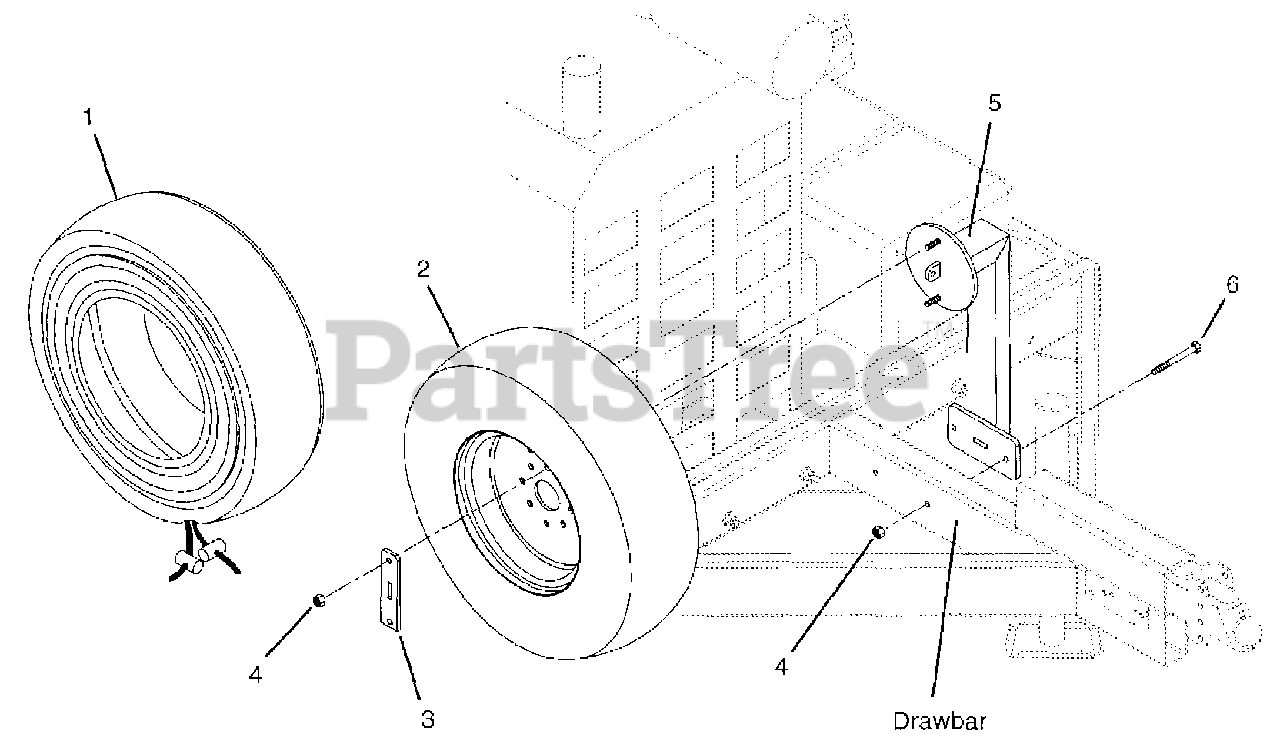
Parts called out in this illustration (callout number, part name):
1	Wheel Cover
2	Tire/Rim Assembly
3	Support Bracket
4	Nut-Locking-Center .50-13
5	Carrier-Spare Tire Weldment
6	Bolt-Hex .50-13 x 3.25 Grade 5
